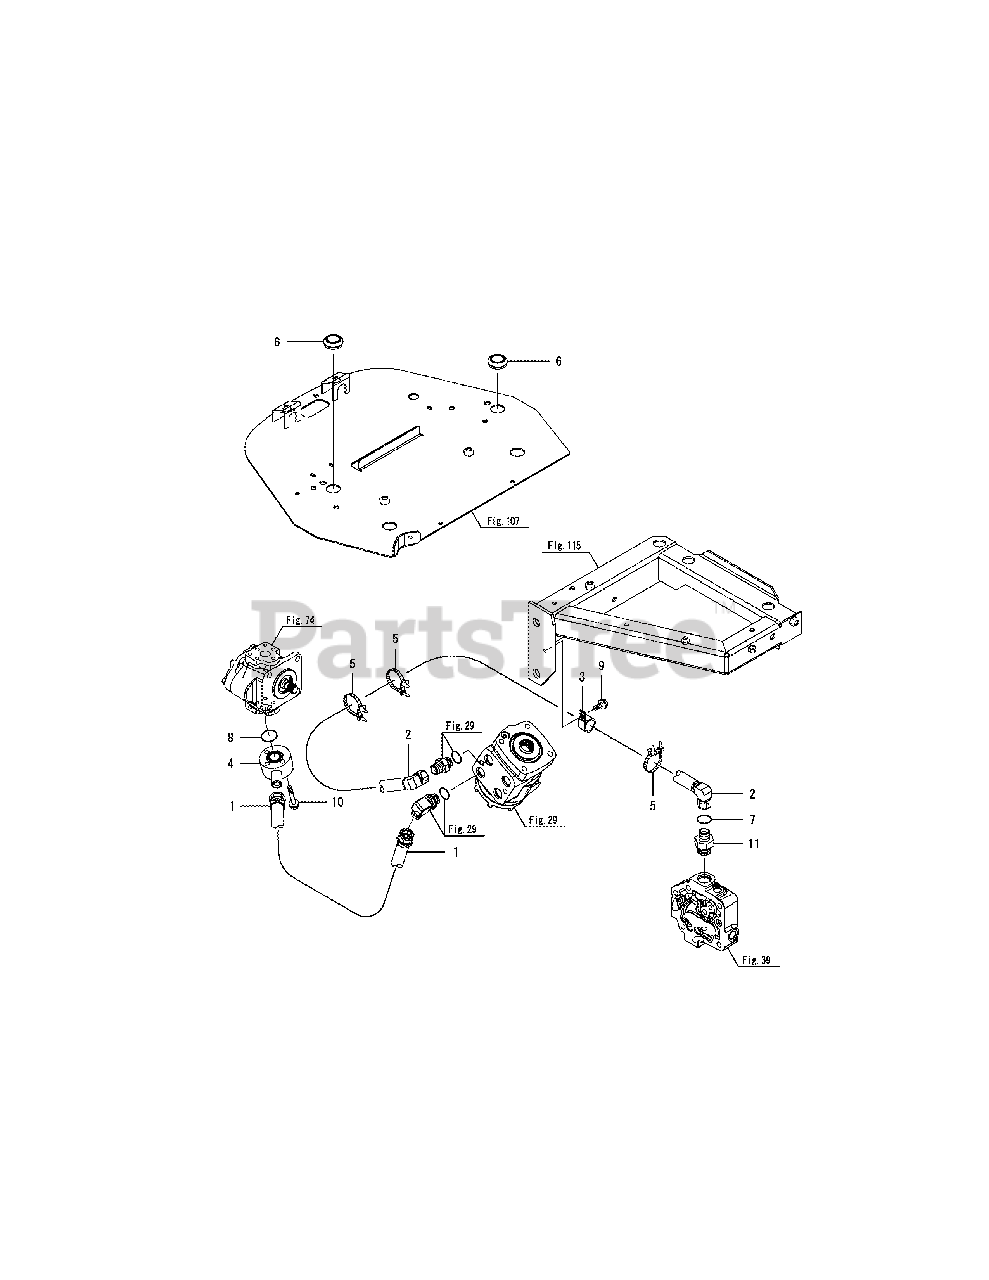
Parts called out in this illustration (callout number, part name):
7	O-RING 1A P-18.0
8	O-RING 1A P-22.0
9	BOLT M 6X 12 PLATED
10	BOLT M 6X 40 PLATED
11	CONNECTOR PF1/2-3/8
